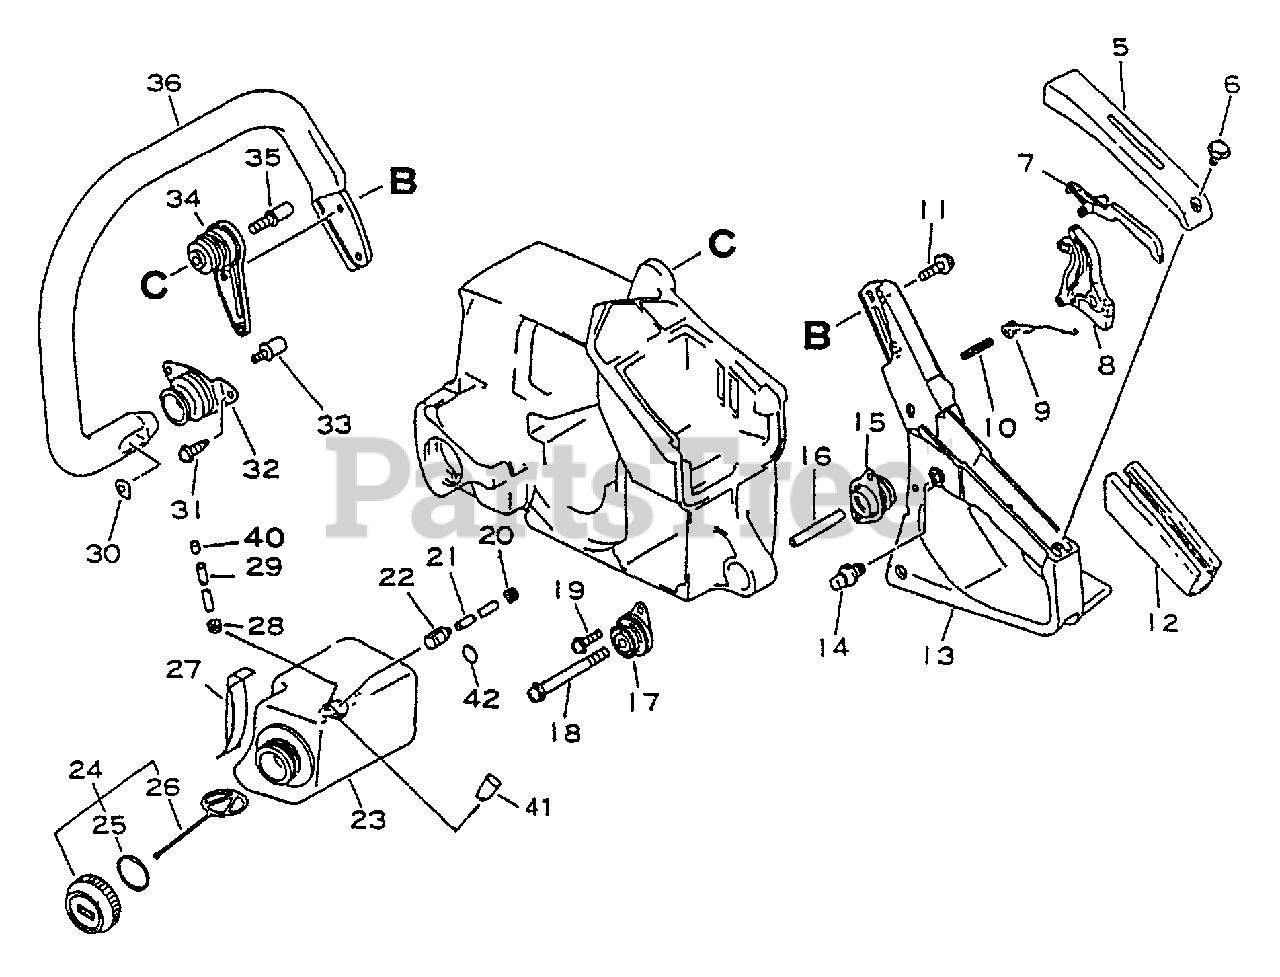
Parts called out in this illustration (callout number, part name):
5	COVER, HANDLE
6	SCREW 4×14
7	LEVER, THROTTLE LOCKOUT
8	TRIGGER, THROTTLE
9	SPRING, THROTTLE RETURN
10	PIN, SPRING 4×30
11	BOLT 5×22
12	GRIP, HANDLE
13	HANDLE, REAR
14	LOCK, THROTTLE TRIGGER
15	CUSHION
17	CUSHION, REAR HANDLE
18	SCREW 5×70
19	SCREW 4×28
21	PIPE, FUEL 3×6×230
22	FILTER, FUEL
23	TANK, FUEL
24	CAP ASSY, FUEL
25	O-RING 22
26	CONNECTOR, CAP L= 60 MM
27	BRACKET, FUEL TANK
28	GROMMET, PULSE
29	PIPE, VENT
30	NUT 5 MM
31	SCREW 5×20
34	CUSHION
35	SCREW
36	HANDLE - FRONT
40	FILTER, VENT
41	PLUG
42	CLIP Ø6.5 MM
